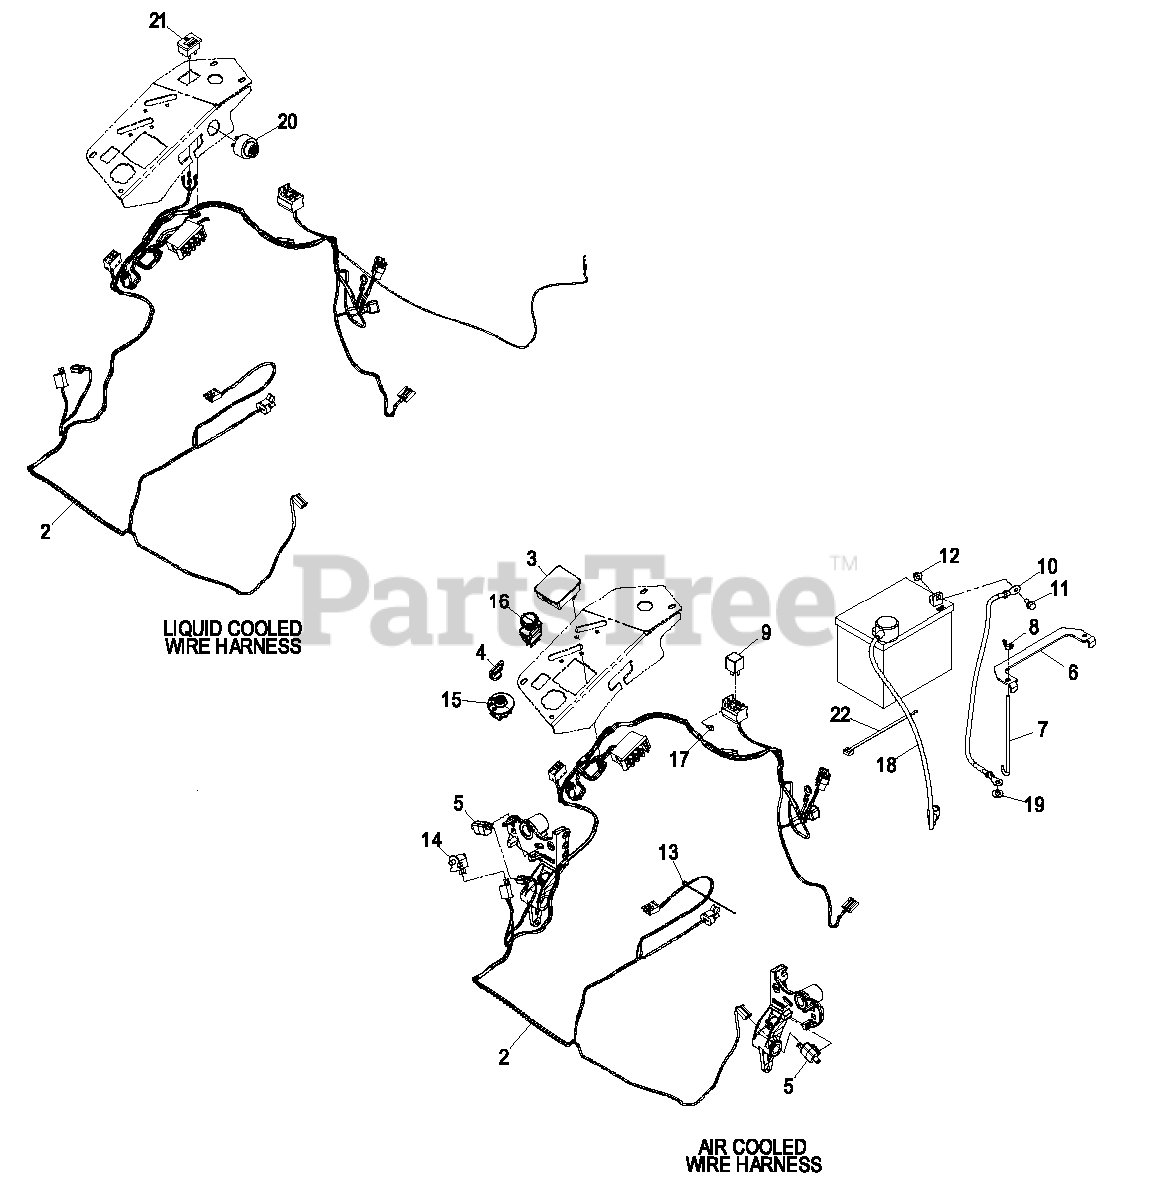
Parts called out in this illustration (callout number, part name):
2	HARNESS-WIRE, MAIN
2:2	FUSE-BLADE, 10 AMP
2:3	FUSE-BLADE, 15 AMP
2:4	FUSE-BLADE, 25 AMP
2:5	CAP-PLUG
4	KEYS-IGNITION (SPARE PAIR
6	STRAP-TIE DOWN, BATTERY
7	BOLT-HOLDDOWN
8	WINGNUT
10	CABLE-BATTERY, NEGATIVE
11	SCREW-HHF
12	NUT-HF, NI
13	TIE-CABLE
14	SWITCH-BAIL
16	SWITCH-PTO, 10 AMP
17	SCREW-HWH
18	CABLE-BATTERY, POSITIVE
19	WASHER-FLAT
20	ALARM-TONE, DUAL
21	GAUGE-TEMPERATURE
22	TIE-PLASTIC
